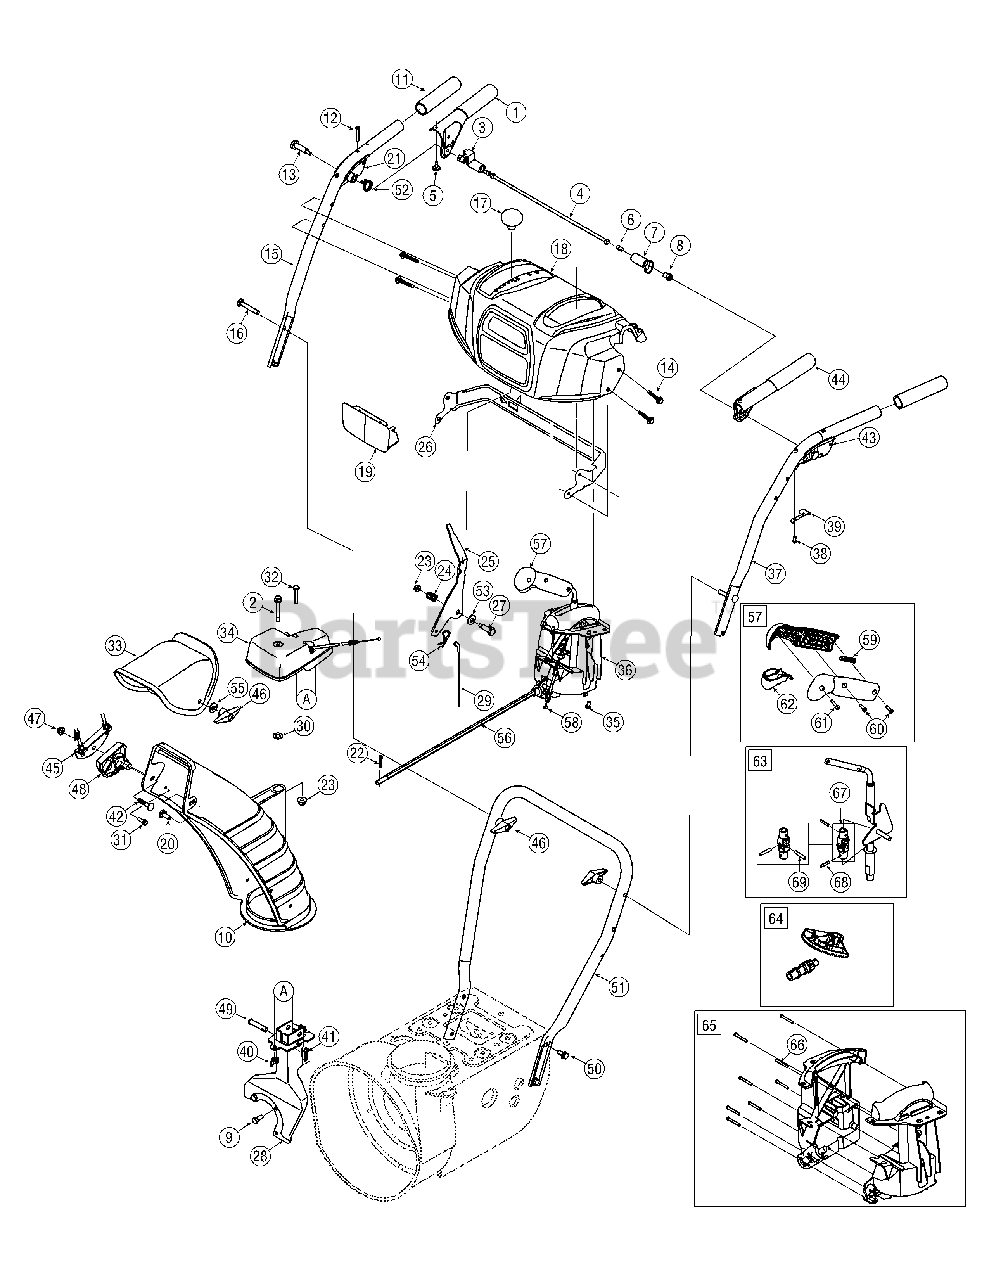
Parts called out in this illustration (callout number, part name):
1	Handle Engagement Assembly RH
2	Flange Shoulder Screw
3	Lock Plate
4	Pivot Rod
5	Rubber Bumper
6	Screw, 1/4-20 x .500
7	Clutch Lock Cam
8	Shoulder Nut, 1/4-20
9	Hex Screw, 5/16-24 x .750
10	Lower Chute
11	Handle Grip
12	Screw, #10-24 x 0.375
13	Shoulder Screw, 1/4-20
14	Screw, 1/4-20 x 1.625
15	Upper Handle RH
16	Carriage Screw, 5/16-18 x 2.25
17	Shift Knob
18	Handle Panel
20	Carriage Bolt, 5/16-18 x 1.0
21	Handle Clutch Lock RH Assy
22	Cotter Pin
23	Flange Lock Nut, 1/4-20
24	Compression Spring
25	Shift Lever
26	Panel Bracket
27	Shoulder Screw
28	Chute Support Bracket
29	Speed Selector Cable
30	Flat Washer, .25 x .630 x .0515
31	Hi-Lo Screw, 1/4-15 x .75
32	Hex Screw, 1/4-20 x 3.00
33	Upper Chute
34	4-Way Chute Gearbox Assembly
35	Hi-Lo Screw, 1/4-15 x 0.5
36	4-Way Chute Control™ Assembly
37	Upper Handle LH
38	Screw, #8-16 x 0.50
39	Clutch Lock Spring
40	Wing Nut, 1/4-20
41	Bow Tie Cotter Pin
42	Carriage Bolt, 5/16-18 x 1.50
43	Handle Clutch Lock LH Assy
44	Handle Engagement Assembly LH
45	Cable Bracket
46	Wing Knob
47	Flange Lock Nut, 5/16-18
48	Chute Tilt Cable Guide
49	Clevis Pin
50	Screw, 5/16-18 x 0.75
51	Lower Handle
52	Torsion Spring
53	Flat Washer
54	Click Pin
55	Flat Washer, .349 x .879 x .063
56	Chute Rod
57	Handle Assembly
58	4-Way Cable
59	Handle Plunger
60	Screw, Mach., #8-32 x .750
61	Screw, #8 x 1.00
62	Handle Lever
63	Shift Assembly
64	Gear Set Assembly
65	Handle Housing Assembly
66	Screw, #8-18 x 1.250
67	Joint Block Assembly
69	Roll Pin
